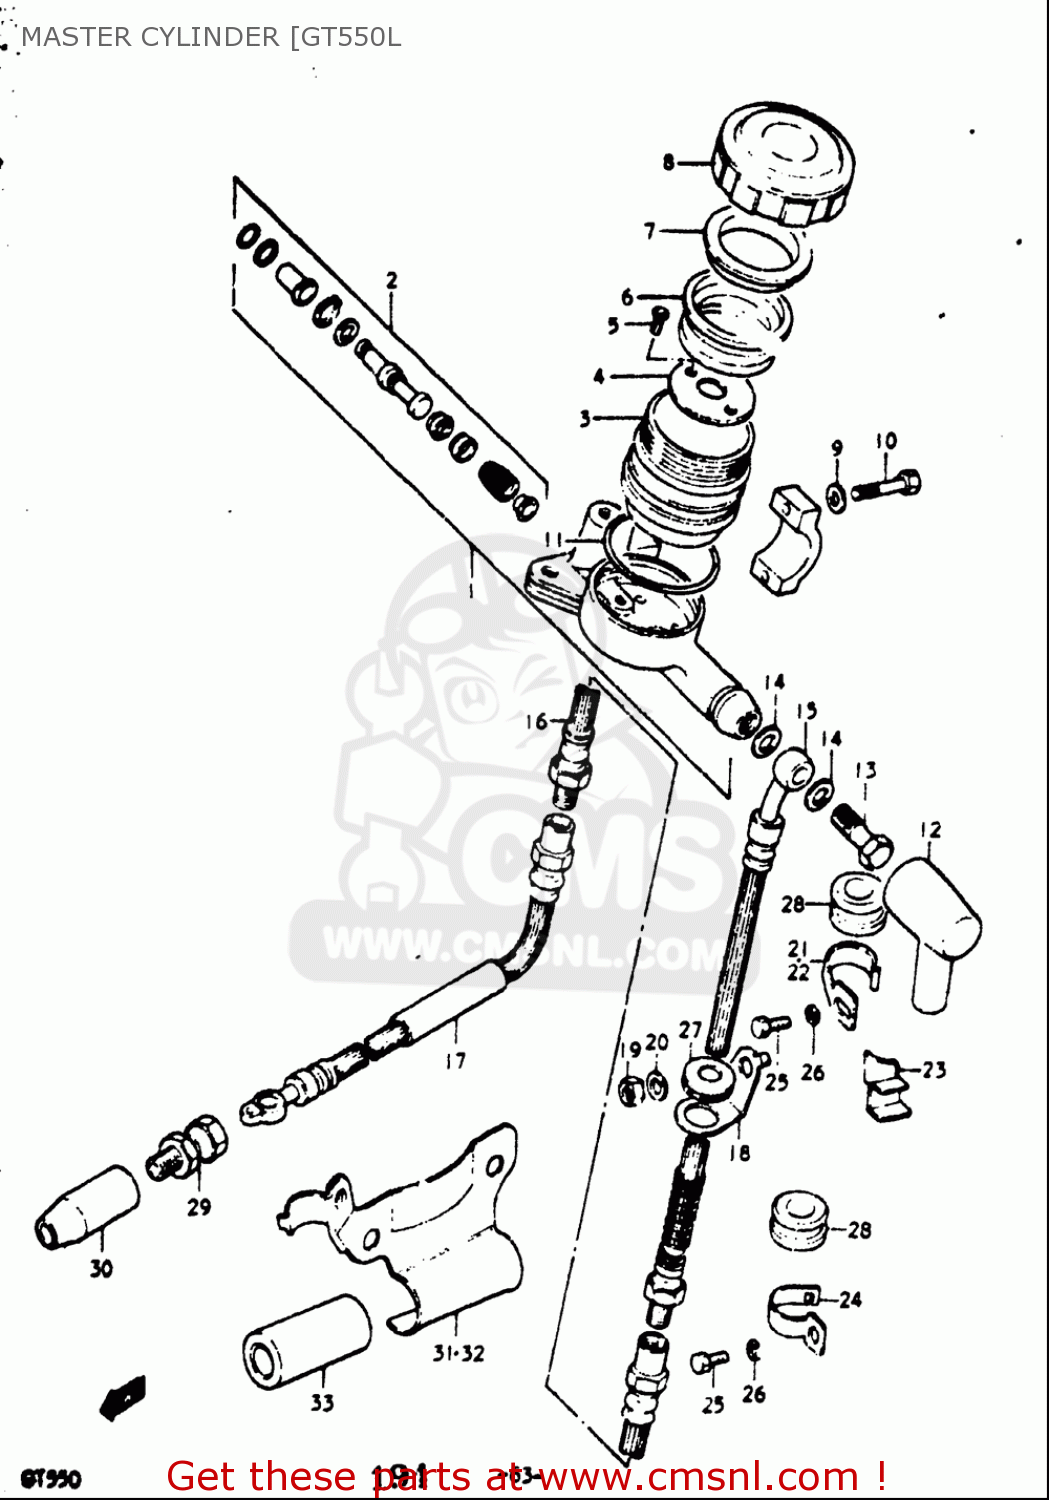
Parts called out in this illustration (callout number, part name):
2	PISTON & CUP SET
3	RESERVOIR
5	SCREW
6	DIAPHRAGM
7	PLATE,DIAPHRAGM
8	CAP
9	WASHER
10	BOLT
11	O RING
12	BOOT,MASTER CYLINDER
13	BOLT UNION
14	WASHER(10X15X1.5)
17	HOSE,BRAKE NO.3
19	NUT
20	WASHER,LOCK
25	SCREW(6X12)
26	WASHER,LOCK
27	GROMMET
28	BUSH
33	CUSHION
